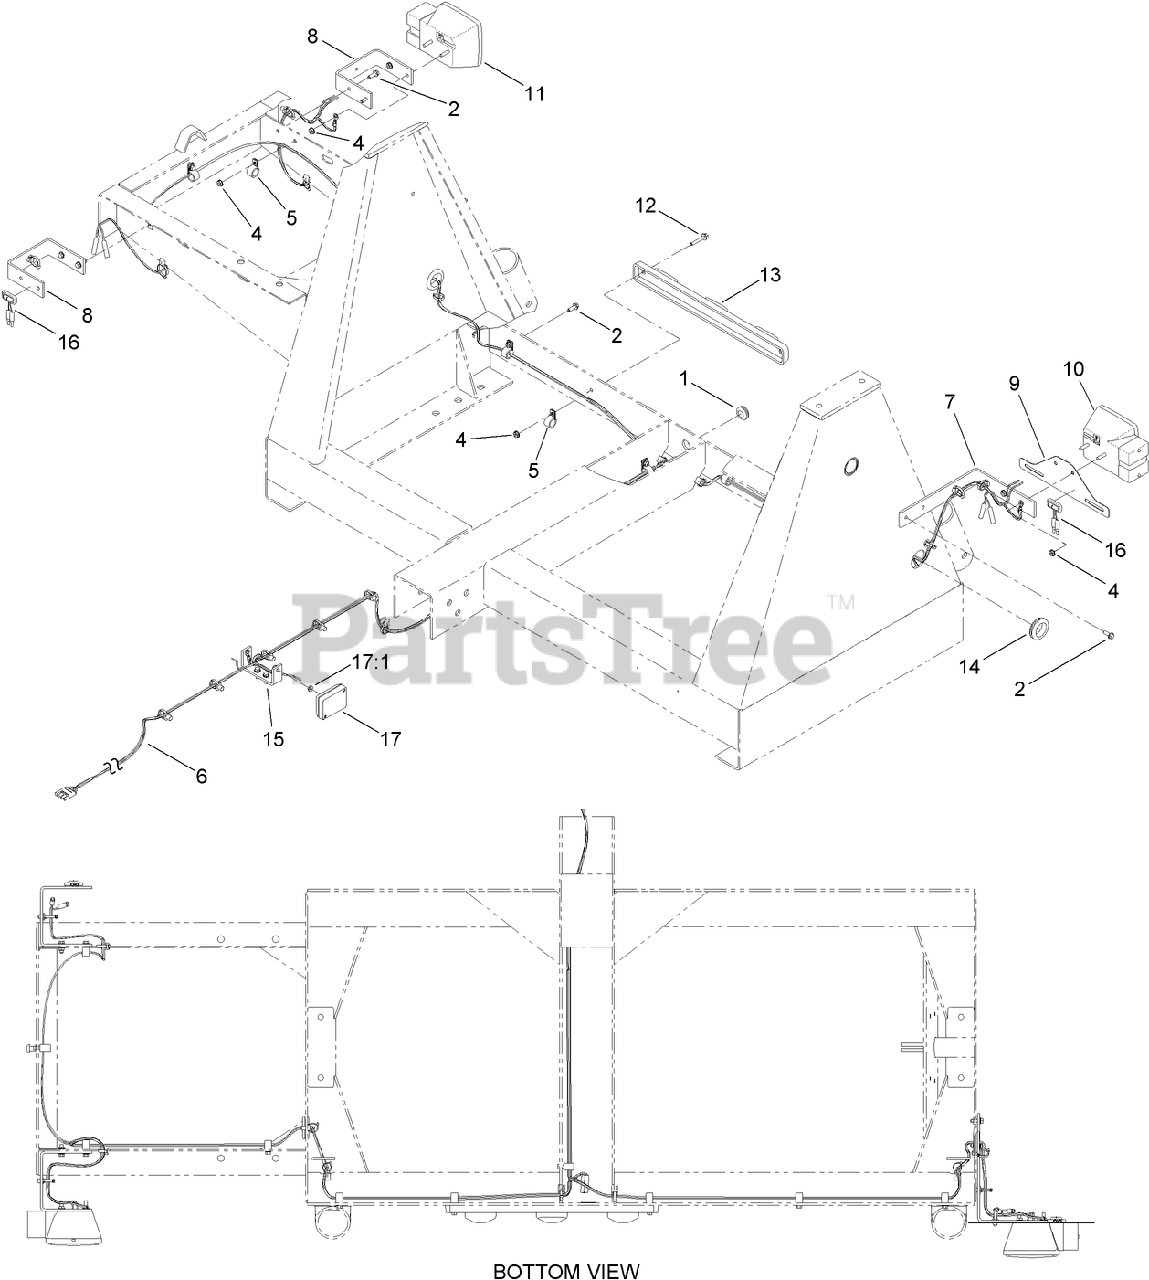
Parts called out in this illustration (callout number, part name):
1	GROMMET
2	SCREW-HHF
4	NUT-KEPS
5	CLAMP-CABLE
6	HARNESS-WIRE
7	BRACKET-L
8	BRACKET-U
9	HOLDER-PLATE, LICENSE
10	LIGHT-TAIL, LH
11	LIGHT-TAIL, RH
12	SCREW-HHF
13	LIGHT-IDENTIFICATION, TRAILER
14	GROMMET
15	BRACKET-LIGHT, END DUMP
16	LAMP-AMBER
17	LAMP-MARKER, FRONT SIDE
17:1	NUT-KEPS
